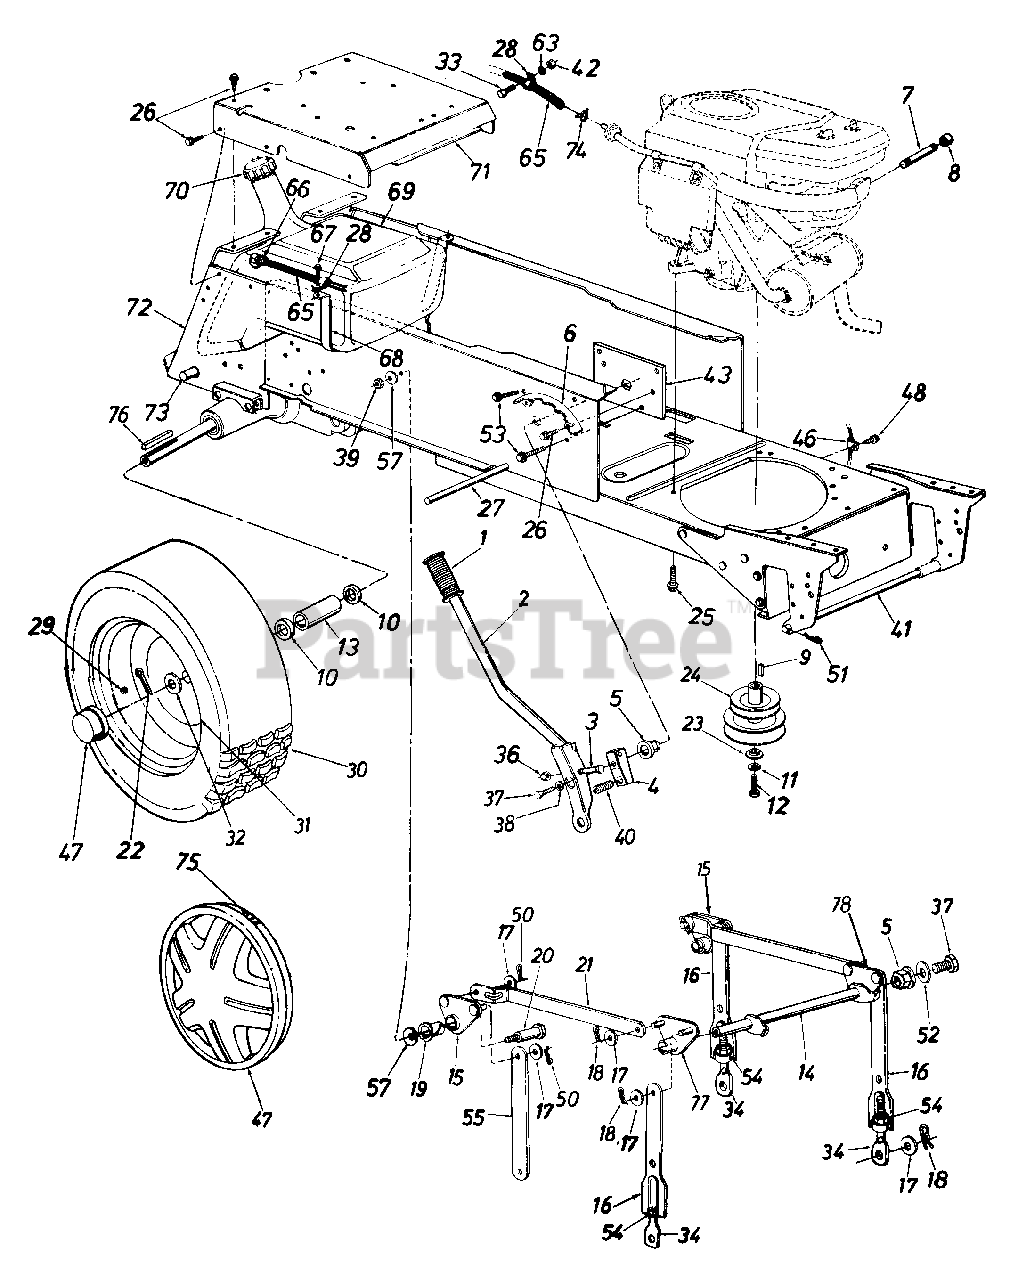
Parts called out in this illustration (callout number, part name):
1	Grip
2	Lift Handle Ass'y.
3	Hex Bolt 5/16-18 x 1.5" Lg.
4	Lift Shaft Drive
5	Plastic Hex Brg. 5/8" I.D.
8	Pipe Cap 3/8-18 Npt.
9	Sq. Key 1/4" x 1/4" x 1.50" Lg.
10	Fl-Wash. 1.03" I.D. x 1.62" O.D.
11	L-Wash. 7/16" I.D.
12	Hex Scr. 7/16-20 x 1.50" Lg.
13	Spacer 1.0" I.D. x 1.25" O.D.
14	Lift Shaft Ass'y.
15	Lift Pivot Brkt. Ass'y.
17	Fl-Wash. 1/2" I.D. x 1.00" O.D. x .090"
18	Hairpin Cotter
19	Flange Brg. 5/8" I.D. x .88" Lg.
20	Shld. Bolt 5/8" Dia. x .96" Lg. 3/8-16
23	Flat Wash. .44" I.D. x 1.25" O.D. x .17"
24	Two-Step Engine Pulley
25	Hex Wash. Hd. Scr. 3/8-16 x 1.25" Lg.
26	Hex Thd. Rolling Scr. 5/16-18 x .75" Lg
27	Running Board Rod
28	Clamp
29	Air Valve - 23" x 9.5" (Round Shoulder)
33	Hex Bolt 1/4-20 x .62" Lg
34	Eye Bolt Adj. Link 1/2-13 Thd.
36	Hex Cent. L-Nut 5/16-18 Thd.
37	Hex Bolt 5/16-24 x .62" Lg.
38	L-Wash. 5/16" I.D.
39	Hex Top L-Nut 3/8-16 Thd.
40	Compression Spring
41	Deck Connecting Rod
42	Hex Nut 1/4-20 Thd.
47	Hub Cap
48	Hex Wash. Hd. TT-Tap Scr. 1/4-20 x .5" Lg
50	Cotter Pin .09 Dia. x 1.0" Lg.
51	Int. Cotter Pin
52	Flat Wash. .34" I.D. x 1.12" O.D. x .125"
53	Hex Wash. Hd. AB-Tap Scr. 5/16-24 x .5" Lg.
54	Hex Nut 1/2-13 Thd.
57	Bell-Wash. .4" I.D. x 1.13" O.D.
63	L-Wash. 1/4" I.D.
65	Fuel Line 46" Lg.
66	Hose Clamp
67	Hex AB-Tap Scr. 1/4 x .62" Lg.
68	Fuel Tank Strap
69	Gas Tank
70	Gas Gauge
74	Hose Clamp
75	Spring Clip
76	Sq. Key 1/4" x 3" Lg.
77	Pivot Brkt. Ass'y. - R.H.
78	Pivot Brkt. Ass'y. - L.H.
